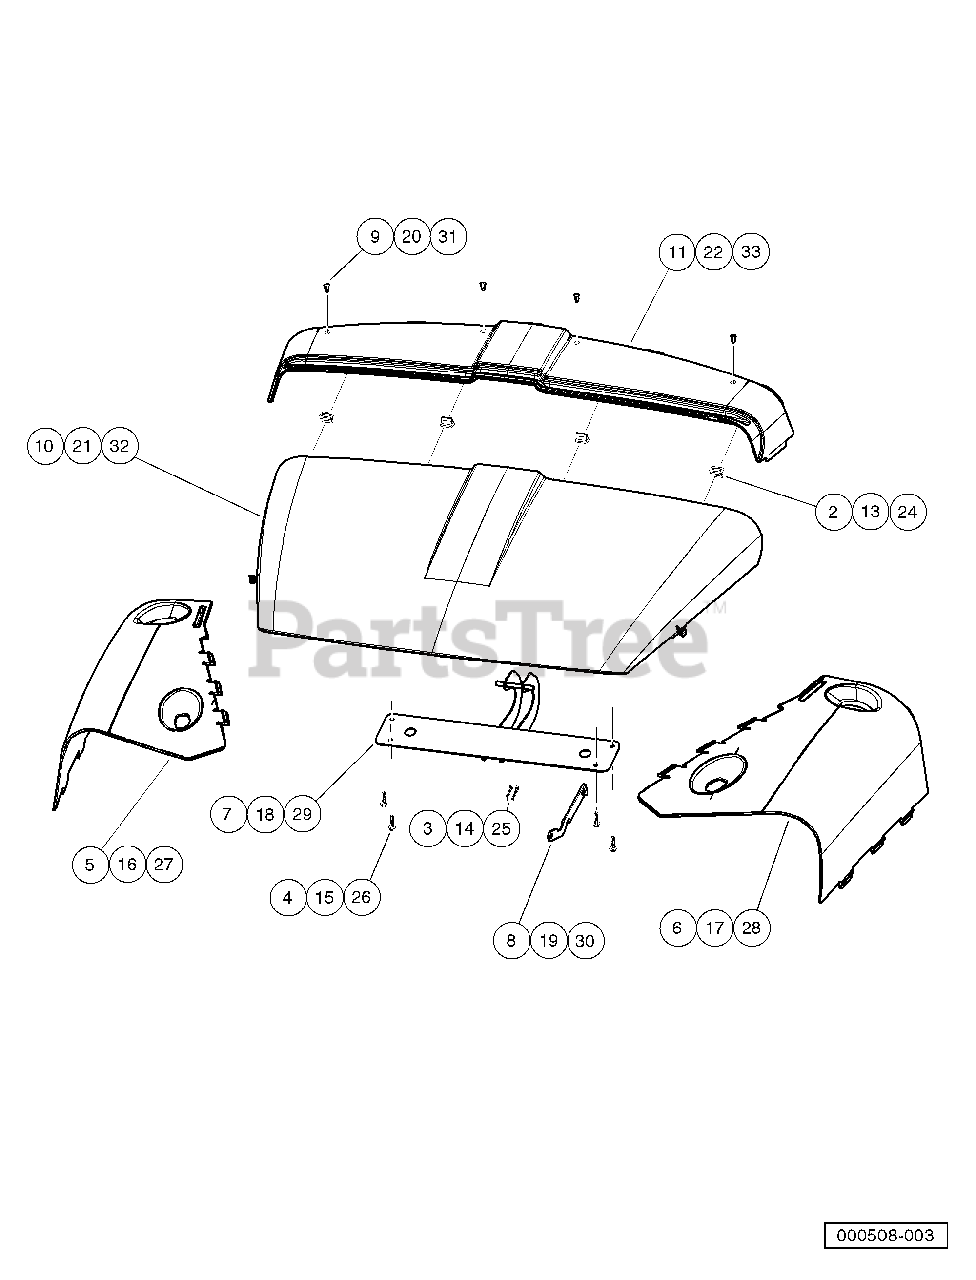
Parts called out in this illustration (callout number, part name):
1	Option, Color, Huv, Camo
2	Clip-body-trim
3	Pin, Bow Tie Locking - .072
4	Screw,m6,torx,interlock,thread
5	Panel, Cowl, Passenger-Side, Camo
6	Panel, Cowl, Driver-Side, Camo
7	Weldment, Hinge, Hood
8	Prop, Hood
9	Rivet, Removable, Tuflok 1/4"
10	Hood, Design B, Moff
11	Panel, Cowl, Upper, B,moff
12	Option, Color, HUV, Orange
13	Clip-body-trim
14	Pin, Bow Tie Locking - .072
15	Screw,m6,torx,interlock,thread
16	Panel, Cowl, Ps, Orange
17	Panel, Cowl, Drv, Orange
18	Weldment, Hinge, Hood
19	Prop, Hood
20	Rivet, Removable, Tuflok 1/4"
21	Hood, Design B, Orange
22	Panel, Cowl, Upper, B, Orange
23	Option, Color, Huv, Olive Grn
24	Clip-body-trim
25	Pin, Bow Tie Locking - .072
26	Screw,m6,torx,interlock,thread
27	Panel, Cowl, Ps, Olive Green
28	Panel, Cowl, Drv, Olive Green
29	Weldment, Hinge, Hood
30	Prop, Hood
31	Rivet, Removable, Tuflok 1/4"
32	Hood, Design B, Olive Grn
33	Panel, Cowl, Upper, B, Olv Grn
